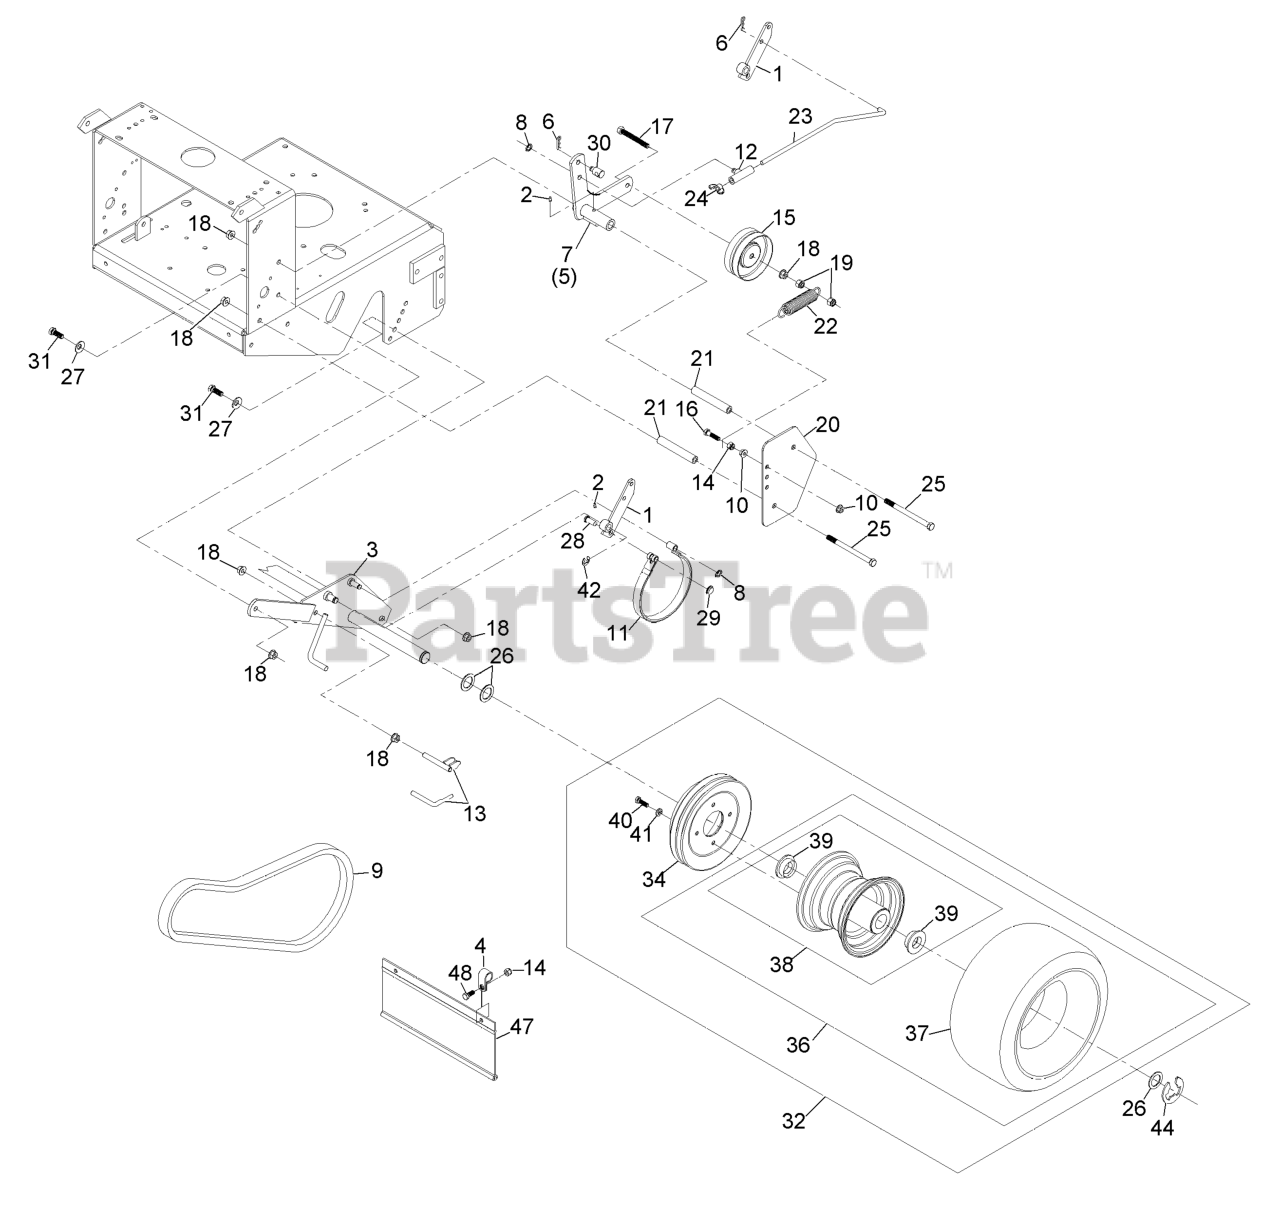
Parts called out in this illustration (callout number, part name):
1	ARM-BRAKE
2	FITTING-GREASE
4	CLAMP-R
5	ARM-IDLER, LH
6	PIN-COTTER
7	ARM-IDLER, RH
8	RING-RETAINING
9	BELT,WHEEL DRIVE
11	BAND-BRAKE
12	SWIVEL-BRAKE
13	SCRAPER
14	NUT-LOCK, NI
15	IDLER-WHEEL, DRIVE
16	SCREW-HH
17	SCREW-HH
18	NUT-HHF, WHIZ
19	NUT-LOCK, NI
20	SHIELD-WHEEL, DRIVE
21	SPACER-SHIELD
22	SPRING-EXTENSION
23	LINKAGE-BRAKE, LH
23	LINKAGE-BRAKE, RH
24	WINGNUT-NYLOCK
25	SCREW-HH
26	WASHER-SPACER
27	WASHER-BELLEVILLE
28	PIN-CLEVIS
29	RING-RETAIN,PUSH,EXT,FLAT
30	SWIVEL-DRIVE LEVER, 3/8 L
31	SCREW-HH
32	DRIVE WHEEL ASM
34	DRUM AND SHEAVE ASM
36	WHEEL AND TIRE ASM
37	TIRE-TURFMASTER
38	WHEEL AND HUB ASM
39	BEARING-FLANGED
40	SCREW-HH
41	WASHER-LOCK
42	RING-RETAINING, EXTERNAL
44	RING-SNAP
47	SHIELD-TRAILING
48	SCREW-HH
